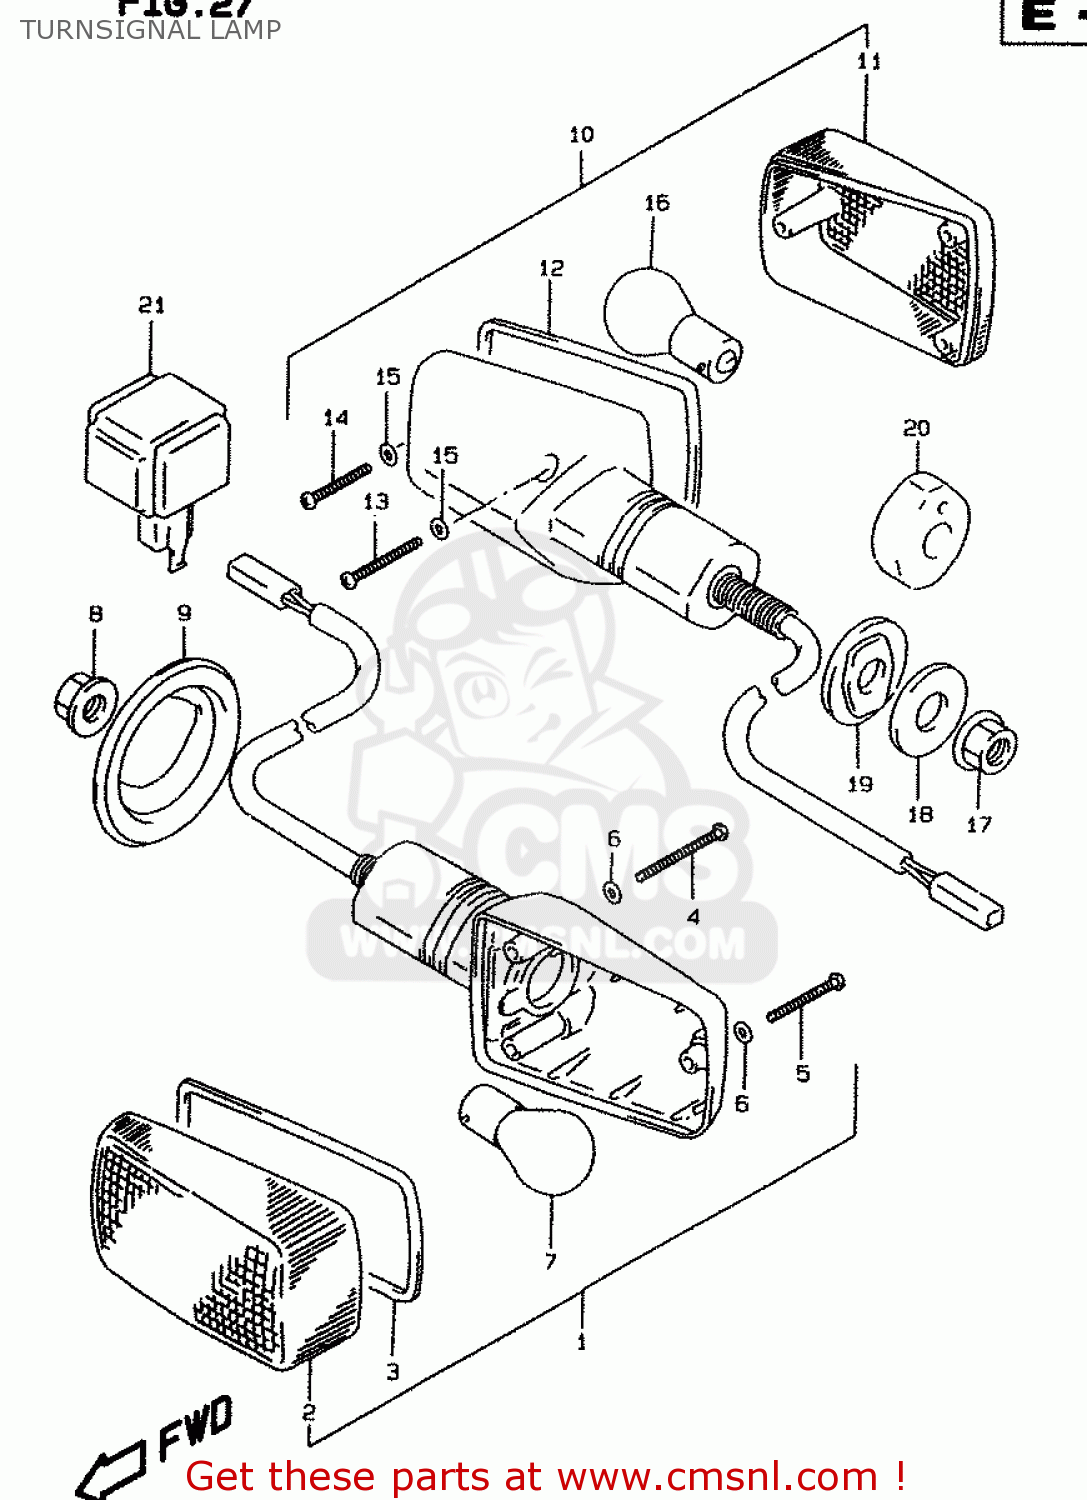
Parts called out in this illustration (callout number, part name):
1	LAMP ASSY,FR TURN SIGNAL
2	LENS
3	GASKET (NAS)
4	SCREW(3X30)
5	SCREW
6	GASKET (NAS)
7	BULB(12V21W)
8	NUT
9	GROMMET
10	LAMP ASSY,RR TURNSIGNAL
11	LENS
12	GASKET (NAS)
13	SCREW(3X30)
14	SCREW
15	GASKET (NAS)
16	BULB(12V21W)
17	NUT
18	WASHER(10.5X30X2.3)
19	SPACER,RR TURNSIGNAL
20	SPACER,FR TURNSIGNAL LAMP
21	RELAY ASSY
